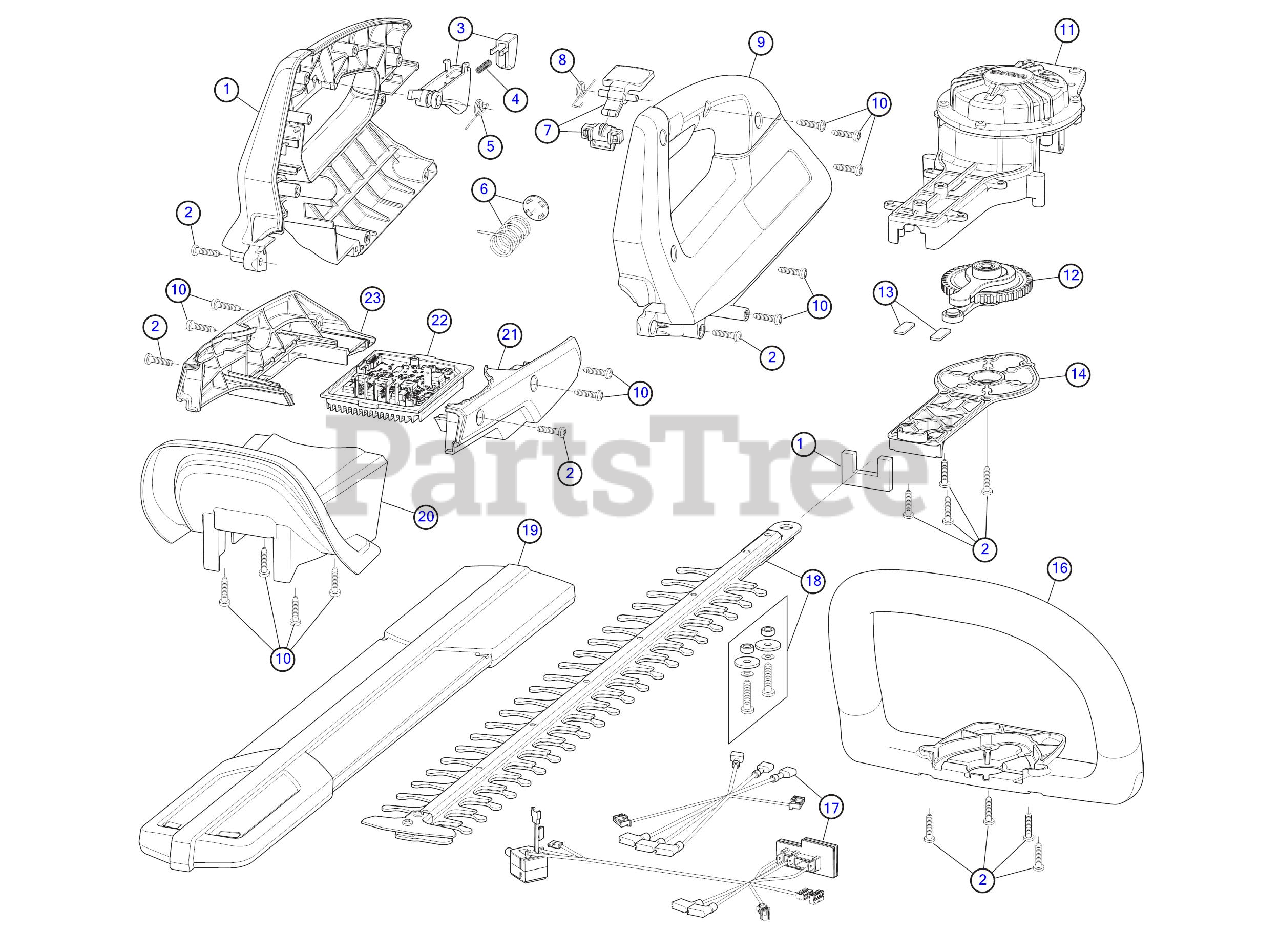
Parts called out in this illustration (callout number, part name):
1	Right Battery Housing
3	Trigger Assembly
4	Lockout Spring
5	Trigger Spring
6	Battery Spring Assembly
7	Battery Latch Assembly
8	Battery Latch Spring
9	Left Battery Housing
11	Motor
12	Gear & Link Assembly
13	Wear Plate
14	Gearbox Plate Assembly
16	Handle
17	Wire Harness Assembly
18	Blade Assembly
20	Guard
21	Left Controller Housing
23	Right Controller Housing
